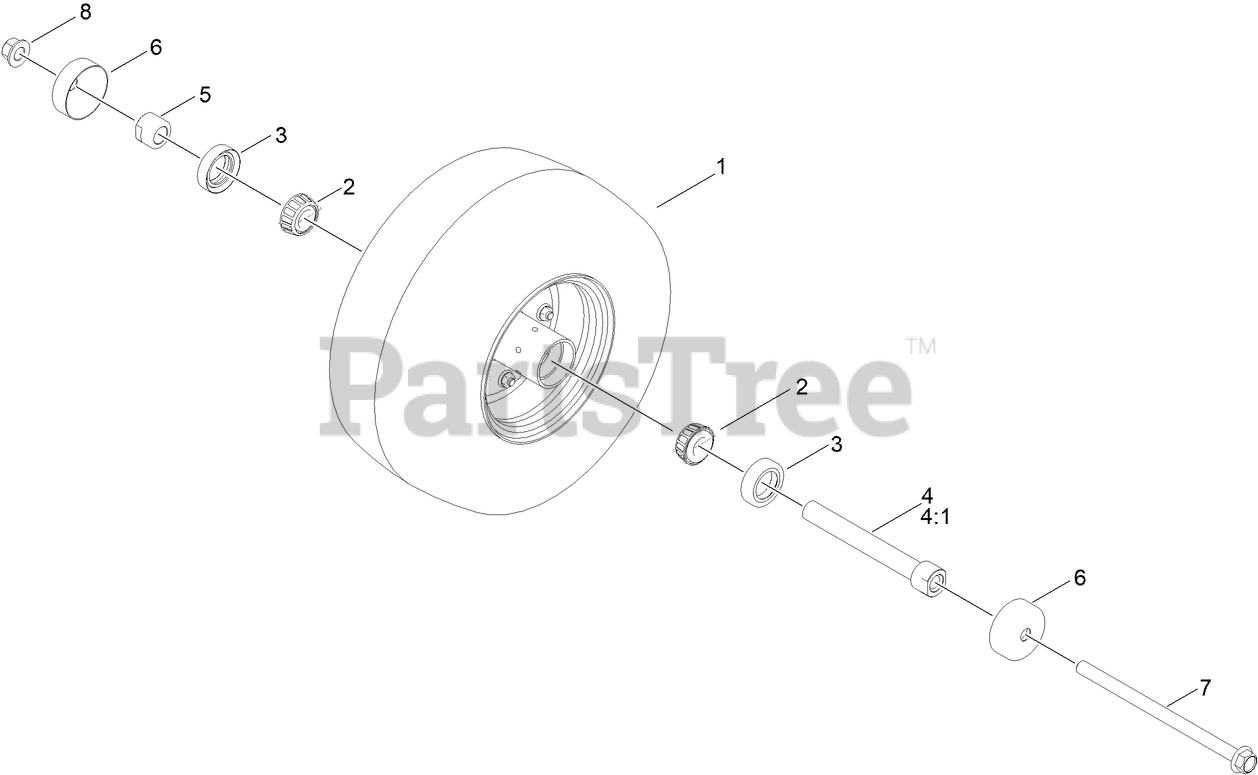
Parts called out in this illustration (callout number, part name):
1	WHEEL 13X6.50-6 SPT GREY
2	BEARING-CONE, TAPER
3	SEAL-CASTER
4	CASTER AXLE ASM
4:1	AXLE-CASTER
5	SPACER-NUT
6	GUARD-SEAL
7	SCREW-HHF
8	NUT-LOCK
